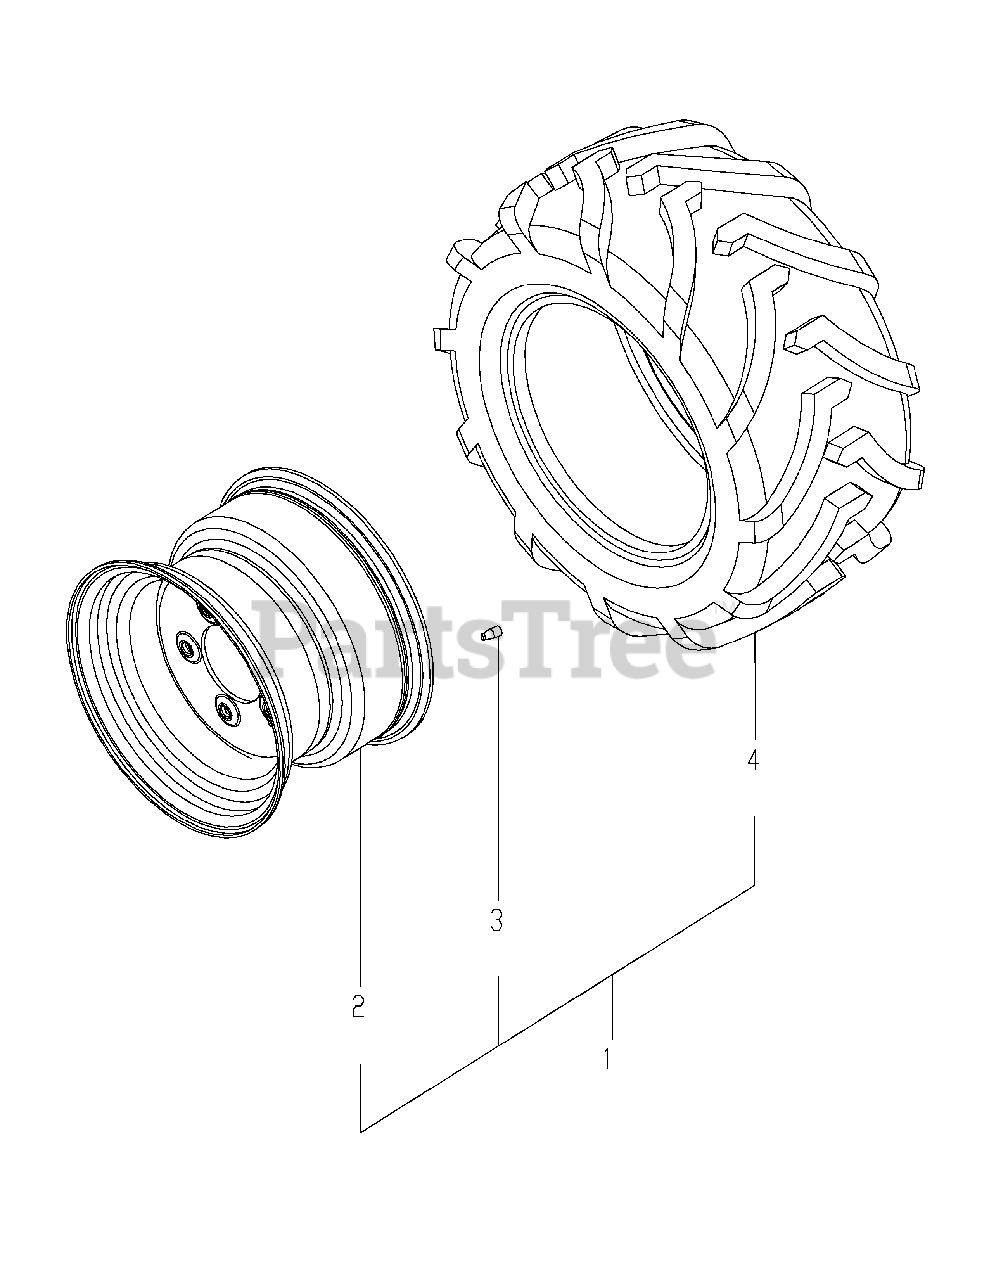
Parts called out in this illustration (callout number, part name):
1	TIRE ASM-FRNT AG LH
1	TIRE ASM-FRNT AG RH
4	TIRE, 18X8.5-10
